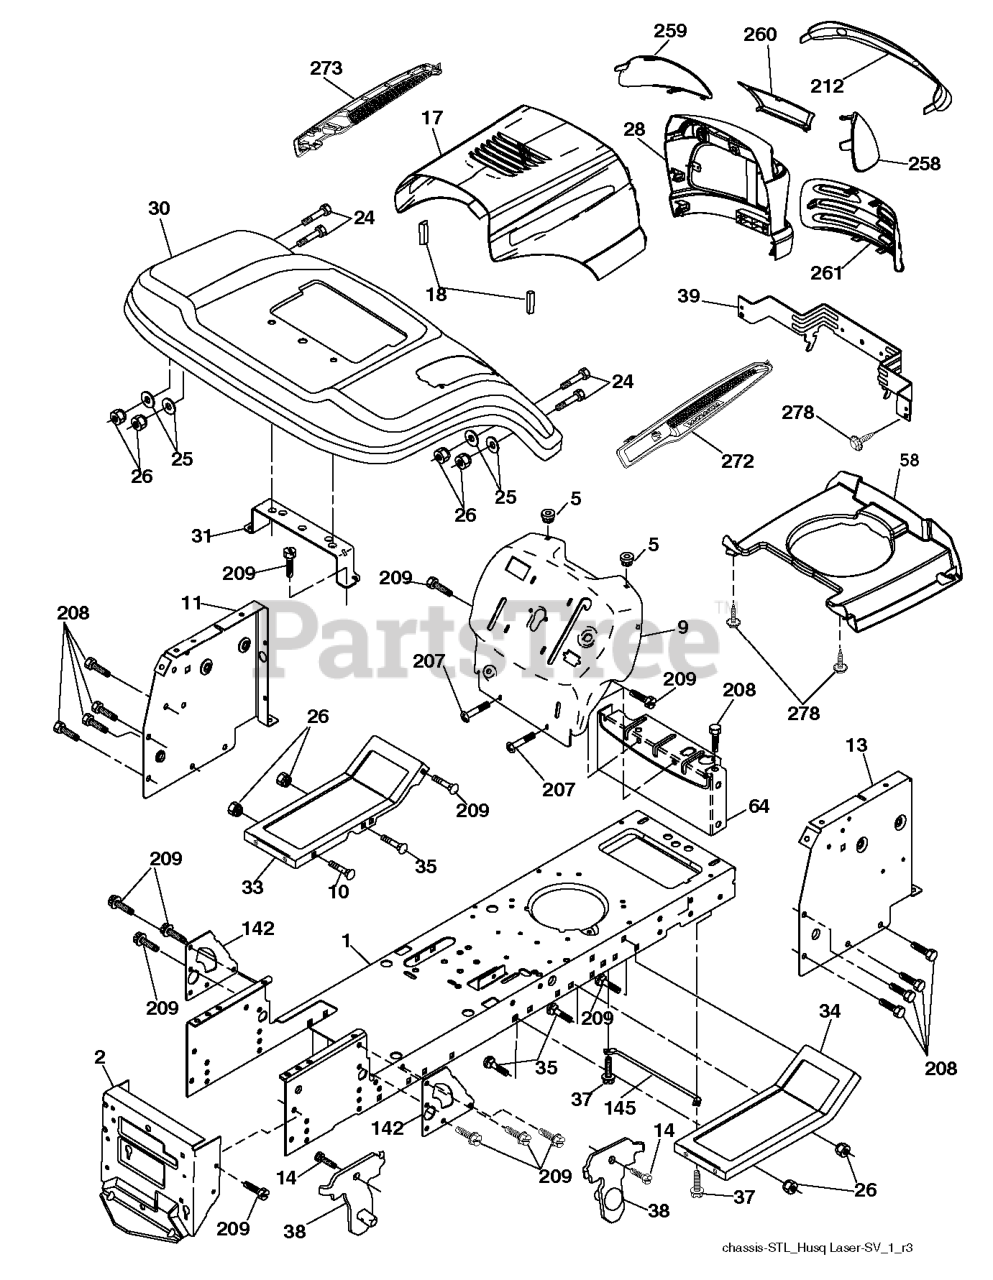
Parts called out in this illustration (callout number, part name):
1	CHASSIS STAMPING
2	DRAWBAR, 12GA
5	BUMPER.RUBBER.HOOD
9	DASH.SLKSCR.SL.PL.C.NA.NHMHUS
10	BOLT D
11	PANEL.DASH.LH.LTX
13	PANEL DASH RH
17	HOOD.PNT.LASER.SV.LT.668
18	BUMPER.HOOD.LARGE.1.75"
25	WASHER
26	NUT
28	GRILLE.HUSQ.LASER.LT.668
30	FENDER.PNT.LTST.W/S.N/C.668ROS
31	BRACKET FENDER
33	FOOTREST.LH.BLACK
34	FOOTREST.RH.BLACK
37	Screw 5/16-18 x 1/2 Hex, Self Tapping 5/16-18 x 1/2
38	BRACKET.ASM.PIVOT.MOWER.REAR
39	BRACKET PIVOT
64	DASH LOWER
142	PLATE REINFORCEMENT
145	ROD.PIVOT.HOOD
207	SCREW, 5/16-18 X 1/2
208	SCREW 3/8-16X1/2
209	SCREW, 3/8-16X3/4
212	INSERT.LENS.REFLECTIVE
258	LENS LH
259	LENS LH
260	COVER.LENS.HUSQ.LASER.LT.498
261	INSERT.GRILLE.HUSQLASER.LT.498
272	VENT.HOOD.LASER.III.SD.RH
278	SCREW.#10 X 0.750.BOS
